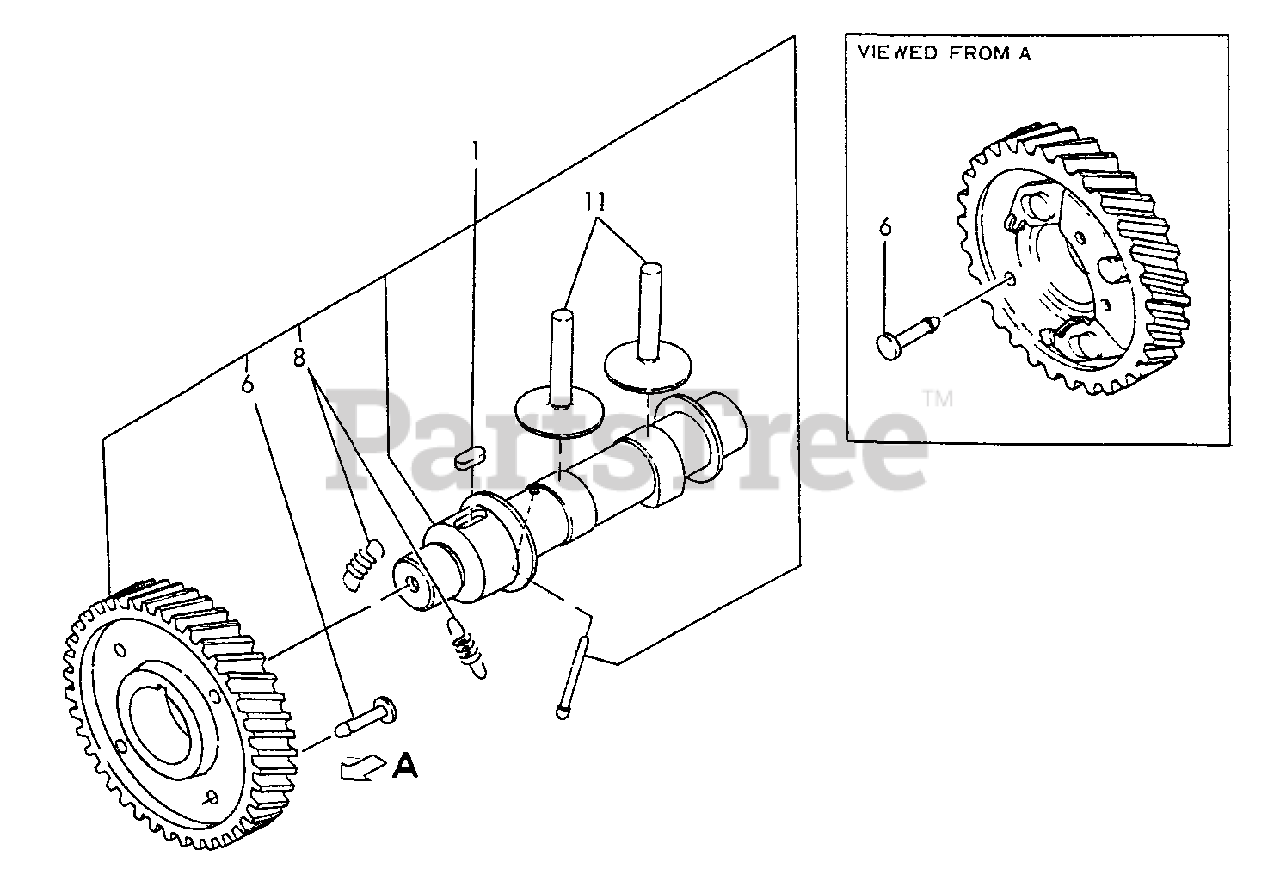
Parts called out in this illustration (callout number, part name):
1	CAMSHAFT ASSY
6	PIN, DECOMP.
8	SPRING
11	TAPPET
